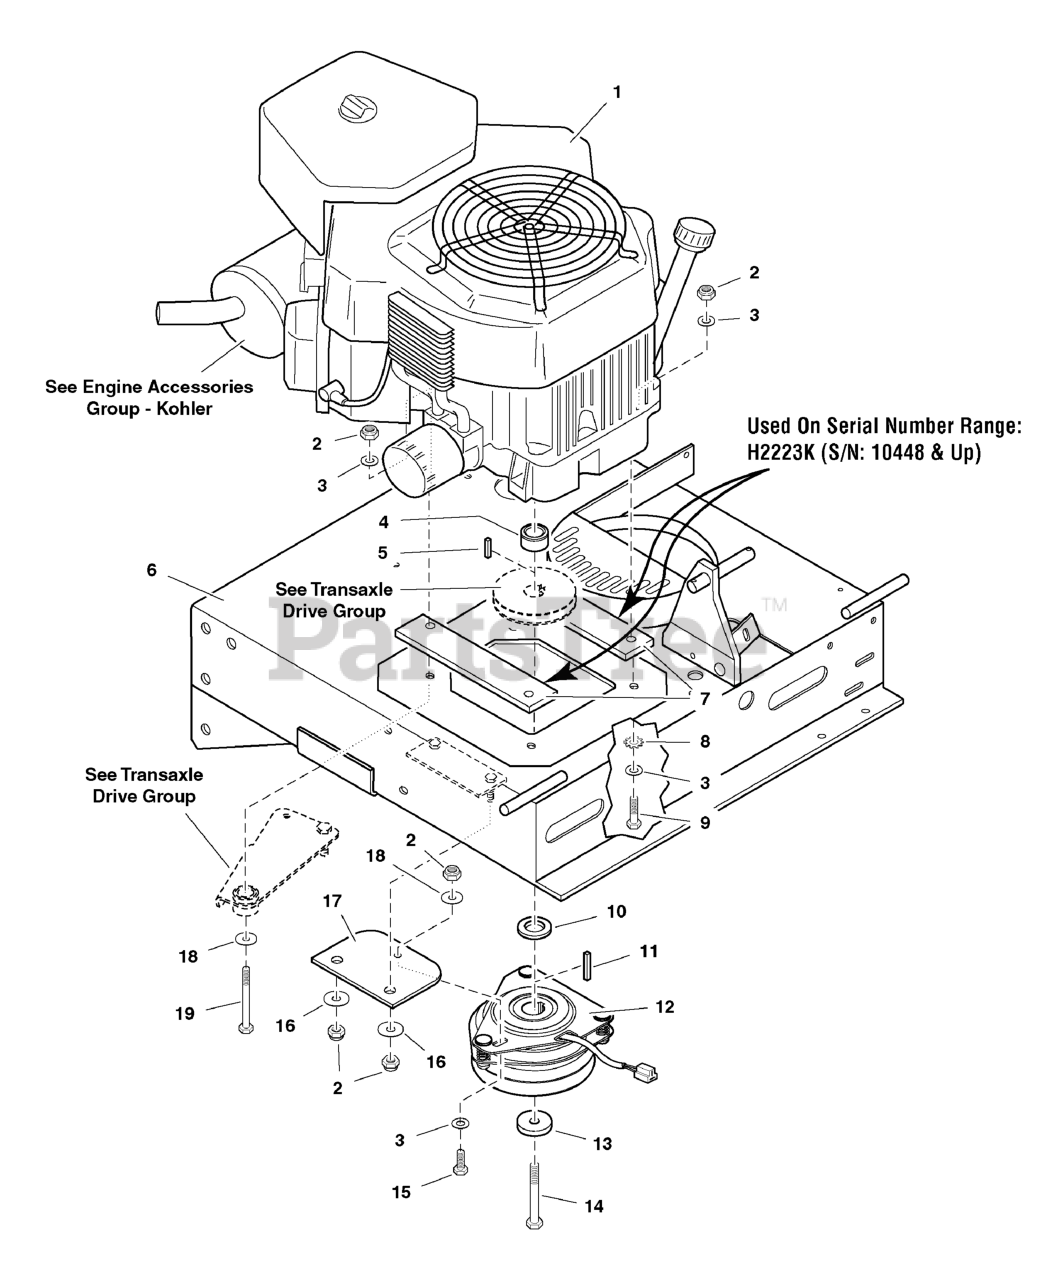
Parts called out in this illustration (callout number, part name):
2	NUT, 5/16-18 Hex Nylon Lock
3	WASHER, 5/16" SAE
4	SPACER, 1.13 x 1.75 x 1.25
4	SPACER, 1.13 X 1.75 X .88
5	KEY, 1/4" SQ. X 1-1/4
6	ENGINE DECK
7	SPACER, Engine Block
8	WASHER, 5/16" Internal Tooth Lock
9	BOLT, 5/16-18 x 2-1/4
9	BOLT, 5/16-18 x 1-3/4
10	SPACER, 1.13 x 1.75 x 1.03
10	SPACER, 1.13 x 1.75 x .62
10	SPACER, 1.13 X 2.00 X .37
11	KEY, 1/4 SQ. x 2-1/4
11	KEY, 1/4 SQ. X 1
12	ELECTRIC CLUTCH
12	CLUTCH, Electric, 1-1/8" Shaft
13	SPACER, .45 x 1.62 x .37
14	CRANKSHAFT BOLT, 7/16 x 2-1/2
14	CRANKSHAFT BOLT, 7/16 x 3
15	BOLT, 5/16-18 X 3/4 GD5
16	WASHER, Clutch Anchor
17	CLUTCH ANCHOR PAD
18	WASHER, 5/16" Fender
19	BOLT, 5/16-18 x 3-1/4
19	BOLT, 5/16-18 x 3
